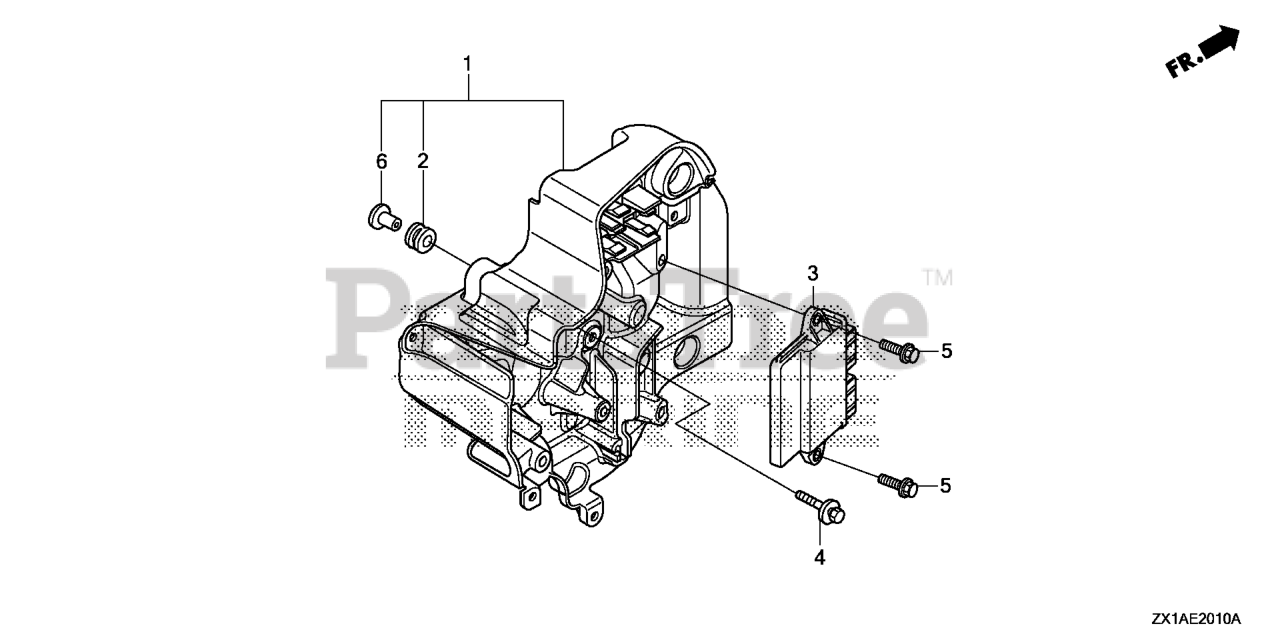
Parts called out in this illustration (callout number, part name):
1	CASE ASSY.
2	GROMMET, ELECTRONIC PARTS CASE
3	CONTROL UNIT, ELECTRONIC
4	BOLT-WASHER (6X27) (CT200)
4	BOLT-WASHER (6X27)
5	BOLT, FLANGE (6X20)
6	COLR, CDI UNIT CASE
6	COLLAR, MODULE IGNITION CONTROL CASE (CDI)
